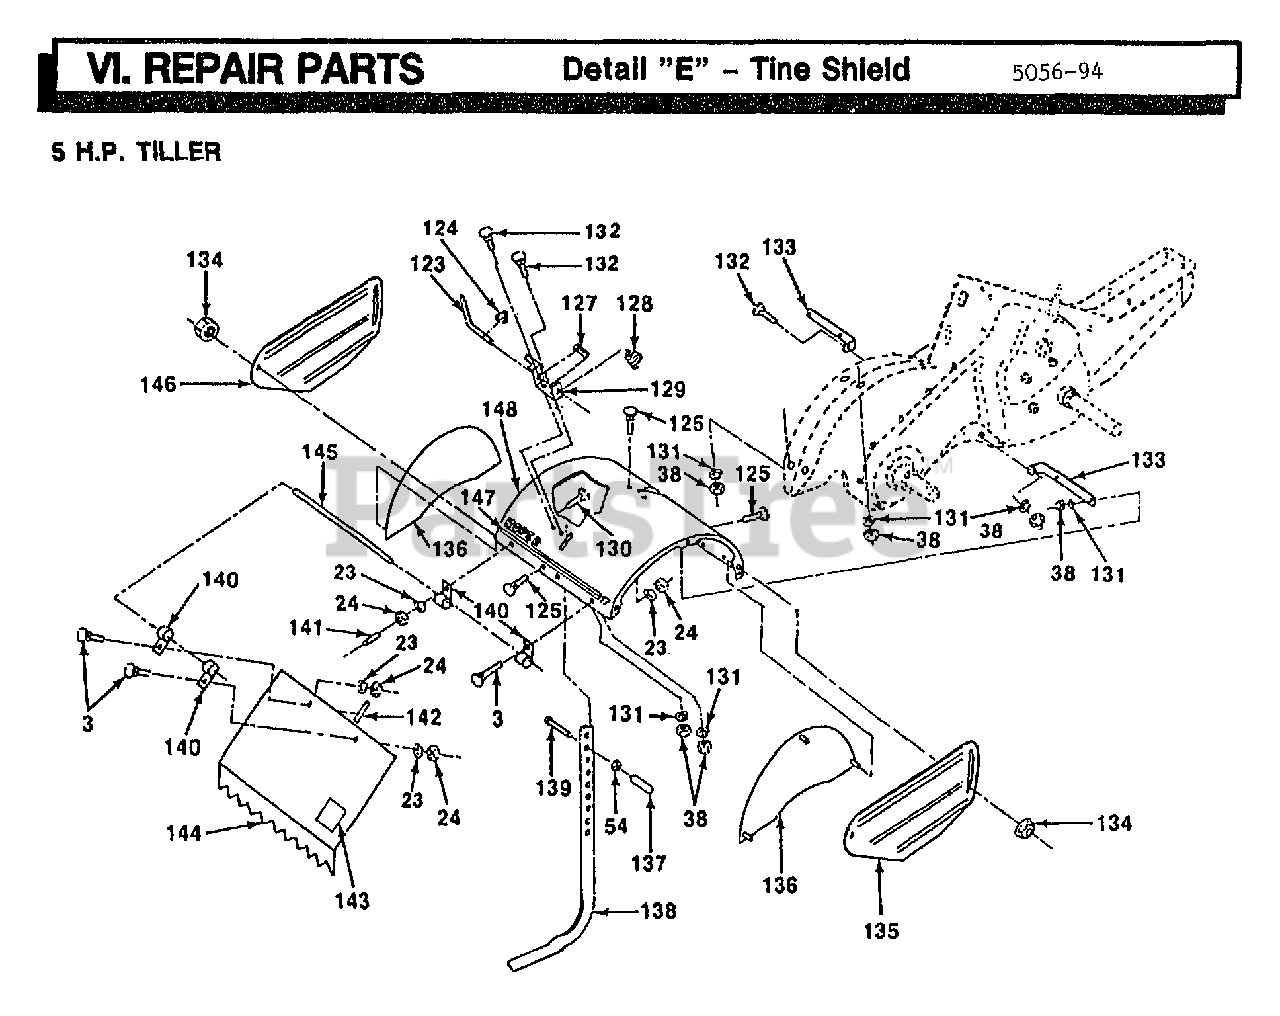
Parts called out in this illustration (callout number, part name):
3	BOLT
23	LOCKWASHER
38	NUT.HEX.5/16-18
54	NUT.HEX.3/8-16UNC
123	STAKE PIN TI
124	KLIP RING TI
125	BOLT
127	SPRING TI
128	SPRING CRT
129	LATCH BRACKET TI
130	BOLT
131	LOCKWASHER
132	BOLT CRT
134	NUT
135	SHIELD.SD.OUT.RH
136	SHIELD CRT
137	GRIP CRT
139	BOLT
140	HINGE CRT
141	VINYL CAP TI
142	PAD IDLER TI
145	PIN HINGE
146	SHIELD.SD.OUT.L
147	DECAL, TINE, SHIELD
